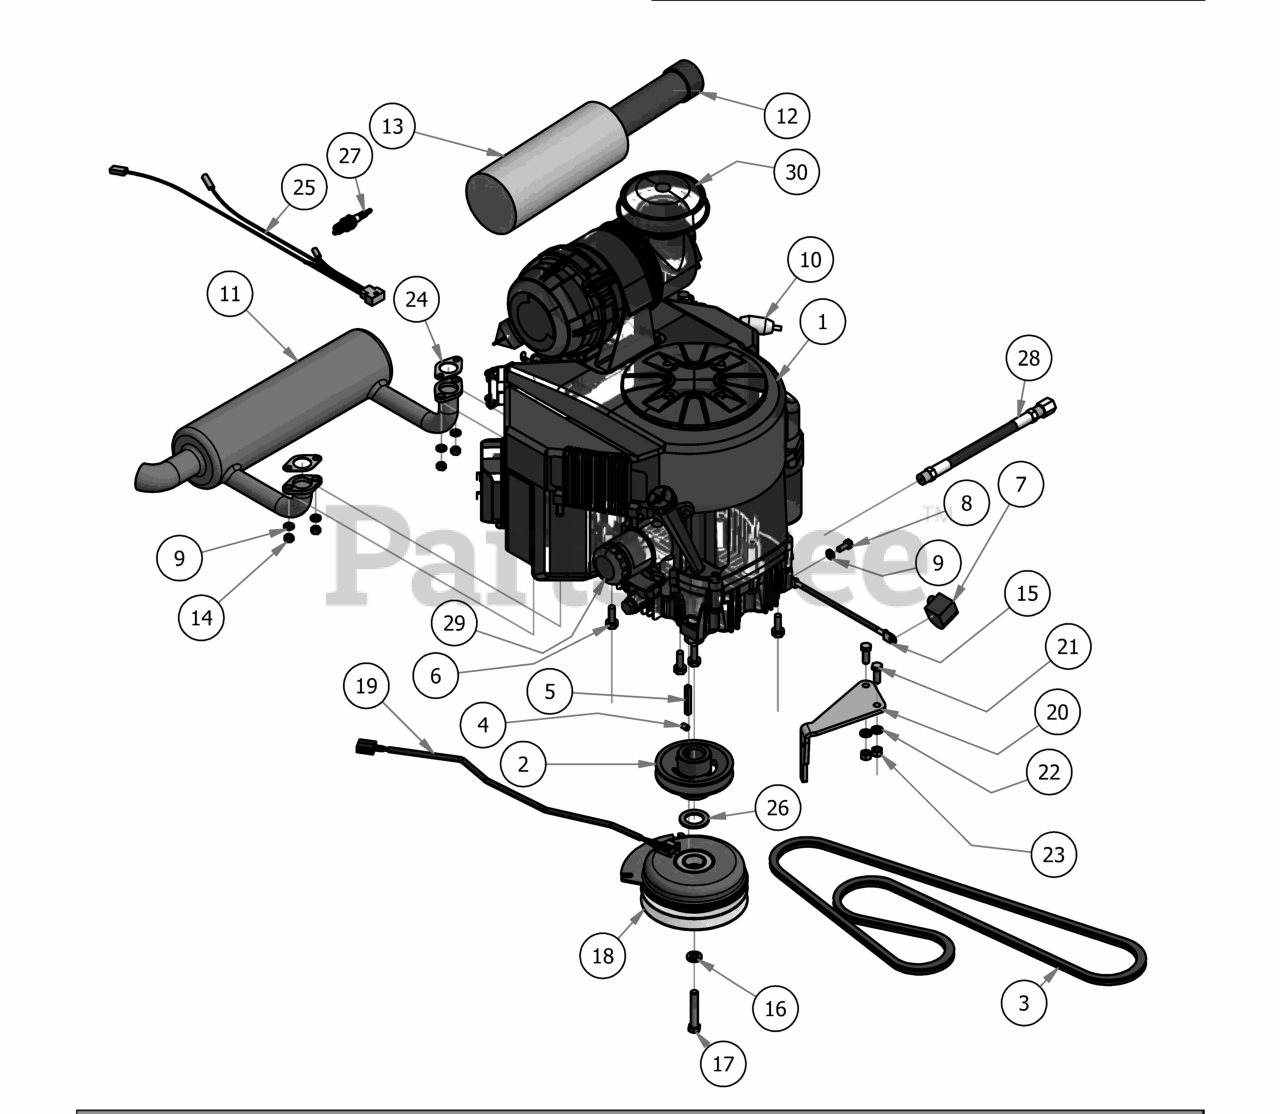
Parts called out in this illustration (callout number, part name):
1	Kawasaki Engine FX-850-V-CS09R
2	4 3/4 Motor Pulley
4	3/8" Set Screw
5	1/4 x 2 Square key Stock
6	3/8 x 1 1/8 bolt
7	Black Boot For Ground Cable
8	M8x1.20x20MM Hex head bolt
9	5/16" Lock Washer
10	Universal Inline Fuel Filter
11	Kawasaki Exhaust
12	Canister Air Filter- Inner
13	Canister Air Filter- Outer
14	M8-1.25 Zinc Nut
15	Ground Cable
16	7/16" Lock Washer
17	7/16" x 2 1/2" Hex Bolt
18	Clutch Assembly
19	Clutch Pigtail
20	PTO Engager Holder
21	3/8" x 1" Hex Bolt
22	3/8" Lock Washer
23	3/8" Hex Nut
24	Exhaust Gasket
25	Harness Adaptor
26	1 1/8" Flat Spacer
27	Spark Plug - Kawasaki
28	Oil drain Hose
29	Kawsaki Oil Filter
30	Kawasaki Rain Cap
